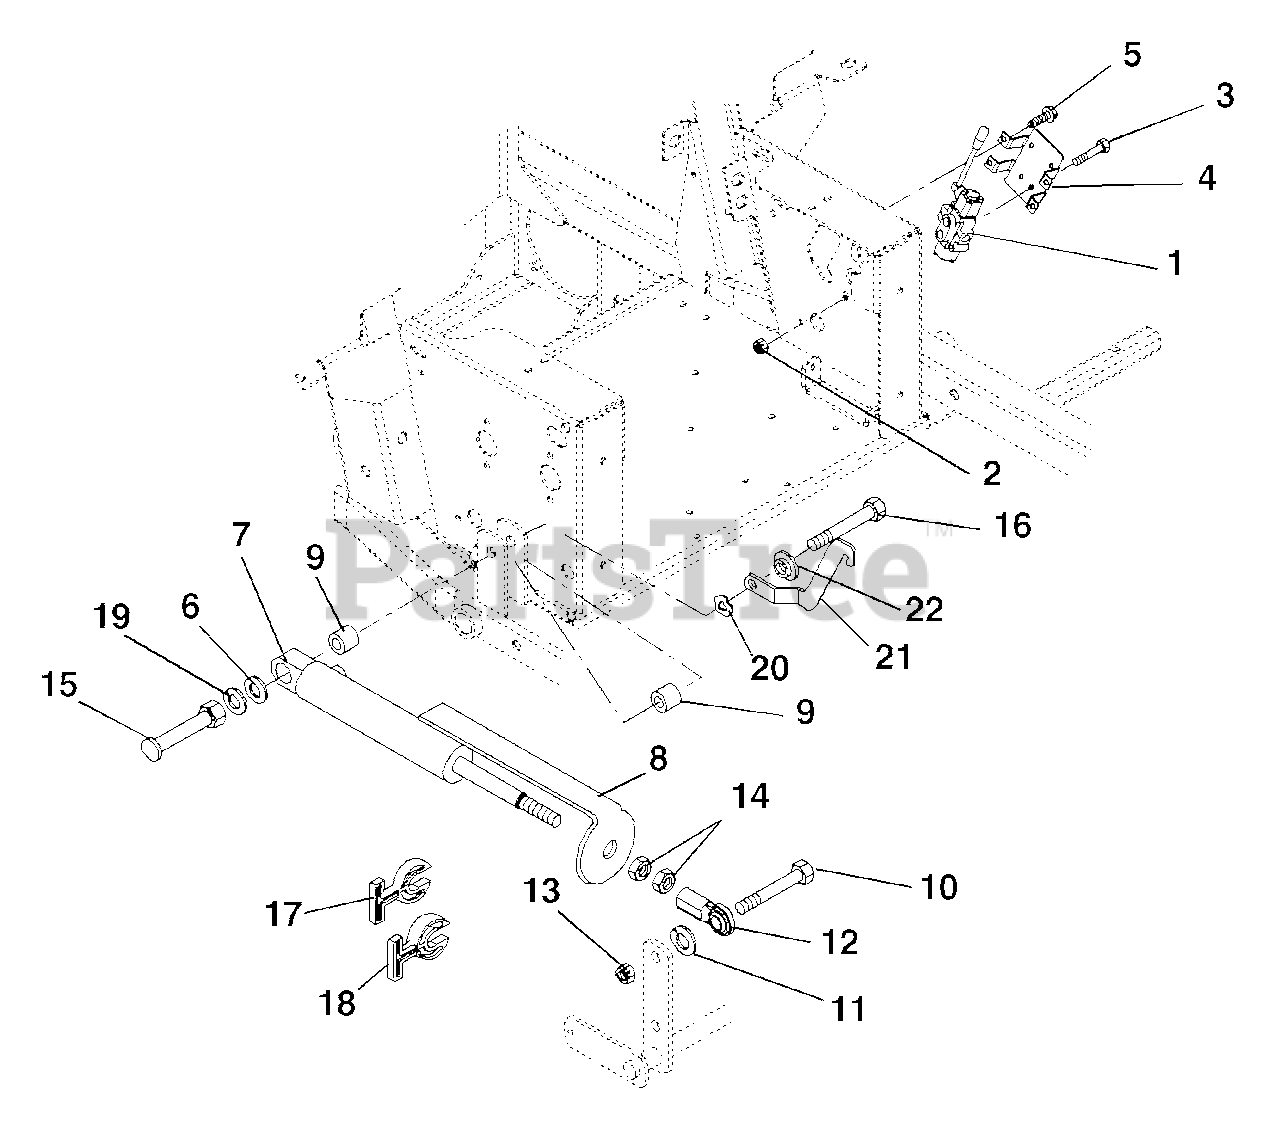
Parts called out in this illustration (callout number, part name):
1	Valve, Hydraulic
2	Nut, Locking Top Flange .31-18
3	Bolt-Hex .31-18 x 2.25 Grade 5
4	Bracket, Valve Mounting
5	Screw-Tapping .38-16 x .50 Hex Washer Head
6	Washer-Flat-Steel .515 x 1.625 x .25
7	Cylinder-Hydraulic Lift
8	Strap-Height of Cut Indicator
9	Bushing .516 x 1.00 x 1.05
10	Bolt-Hex .62-11 x 2.25 Grade 8
11	Washer-Lock .62 x .156
12	Rod End-Right Hand-Female .625
13	Nut-Locking-Center .62-11
14	Nut-Jam .625-18
15	Post, Cylinder Stop
16	Bolt-Hex .50-13 x 3.75 Grade 5
17	Stop, Cylinder .34 Thick
18	Stop, Cylinder .68 Thick
19	Washer, Locking .50 x .125 Regular
20	Washer, Wave .076 x 1.12 x .08
21	Latch, Floor Board
22	Bushing-Flange .515 x .75 x .275 x 1.12
